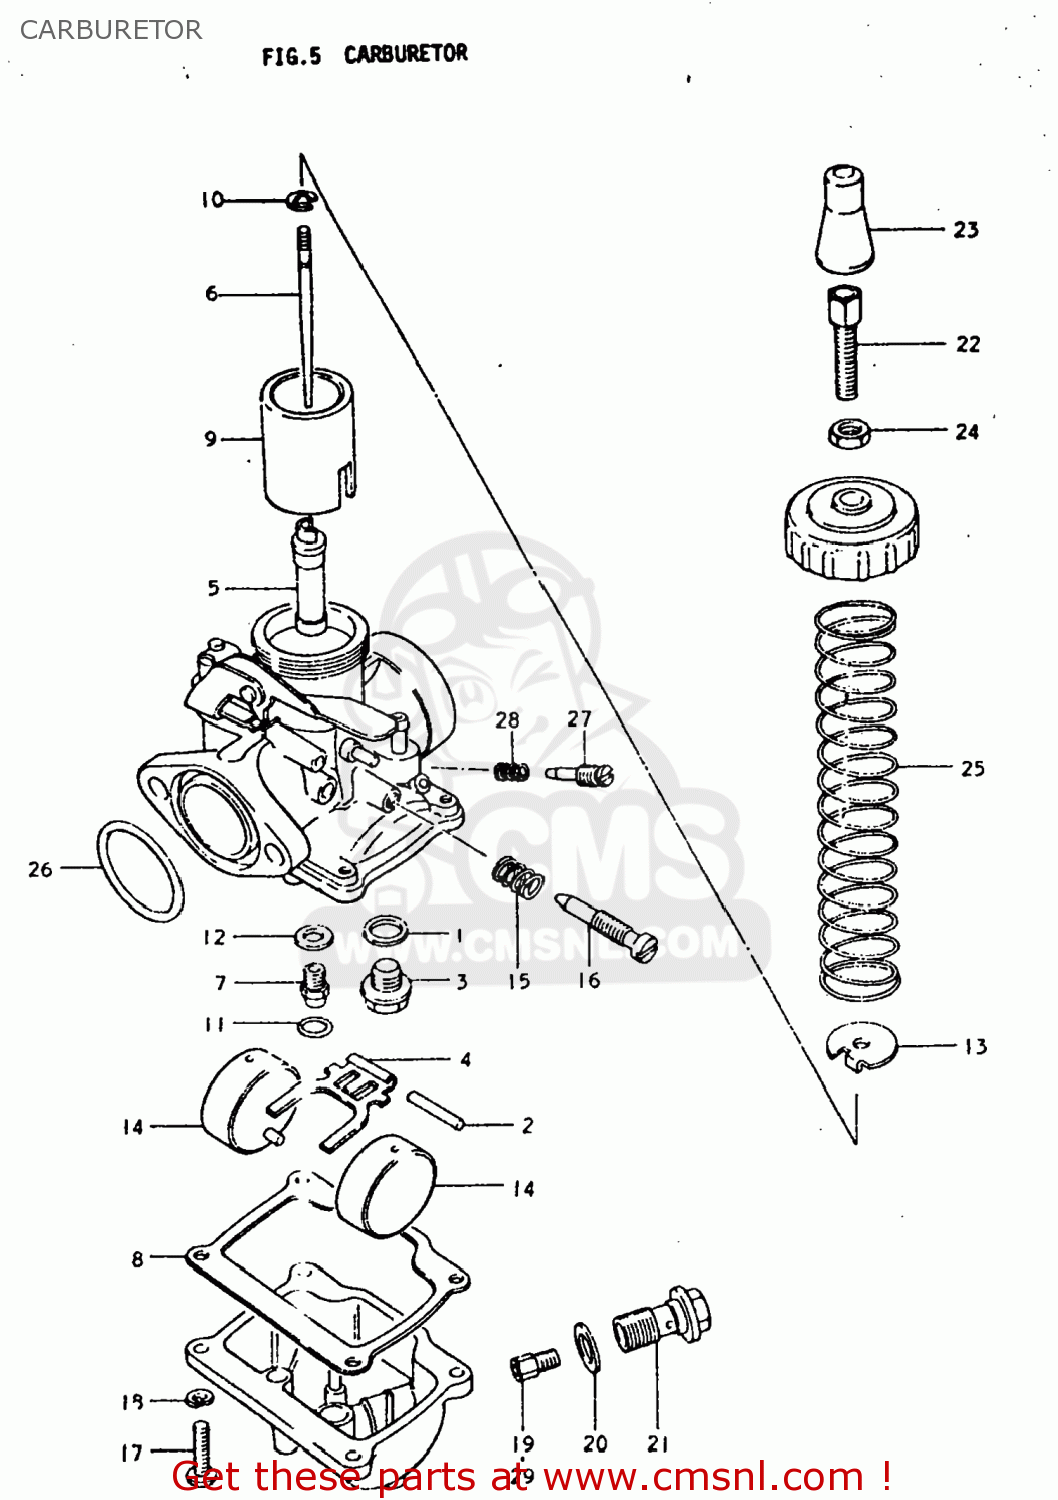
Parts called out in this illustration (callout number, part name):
1	GASKET,VALVE SEAT (NAS)
2	PIN,FLOAT
3	VALVE ASSEMBLY,NEEDLE
4	ARM,FLOAT
5	JET,NEEDLE
6	NEEDLE JET
7	JET
8	GASKET,FLOAT CHAMBER (NAS)
9	VALVE,THROTTLE
10	CLIP
11	O RING
12	WASHER
13	SEAT,THROTTLE VALVE SPRING
14	FLOAT
15	SPRING,THROTTLE SCREW
16	SCREW,THROTTLE STOP
17	SCREW
18	LOCK WASHER
19	JET,MAIN(130)
20	WASHER
22	ADJUSTER,CABLE
23	CAP
24	NUT
25	SPRING, THROTTLE VALVE
26	O RING
27	SCREW,PILOT AIR
28	SPRING
29	JET
